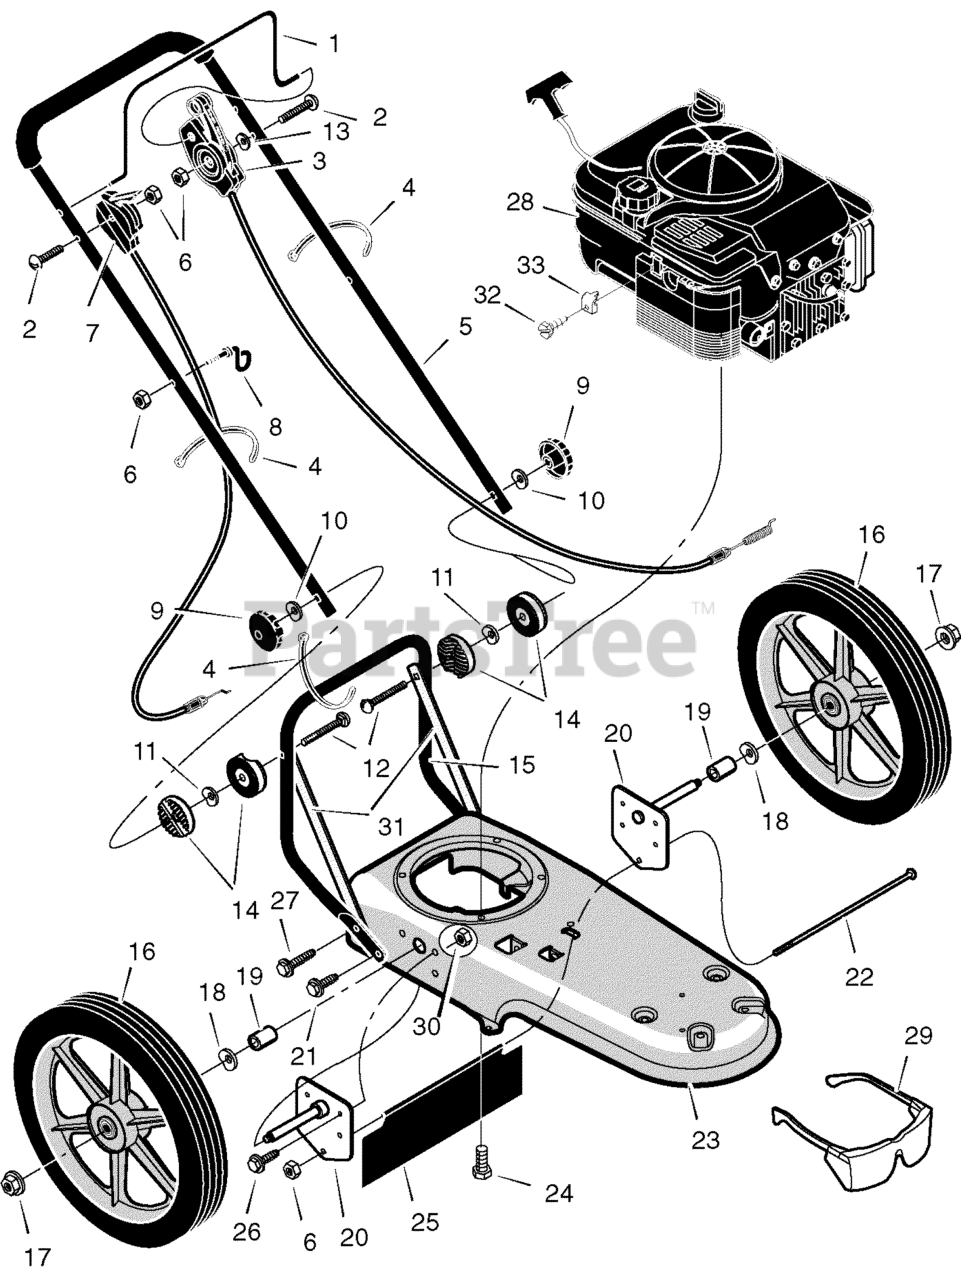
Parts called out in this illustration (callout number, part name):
1	Lever, Stop
3	Cable, Control Latching
4	Tie, Cable
5	Handlebar
7	Control, Throttle
8	Guide, Rope
9	Knob, Handlebar
10	Washer
11	Washer, Spring
13	Spacer
14	Pivot, Handlebar
15	Handlebar, Lower
16	Wheel & Tire
17	Nut, Axle
18	Washer, Spring
19	Spacer
20	Assembly, Axle & Bracket
22	Bolt, Carriage
25	Shield, Trailing
26	Bolt
27	Screw
28	Engine
29	Glasses, Safety
30	Nut
31	Support, Handle
33	Clamp, Throttle
